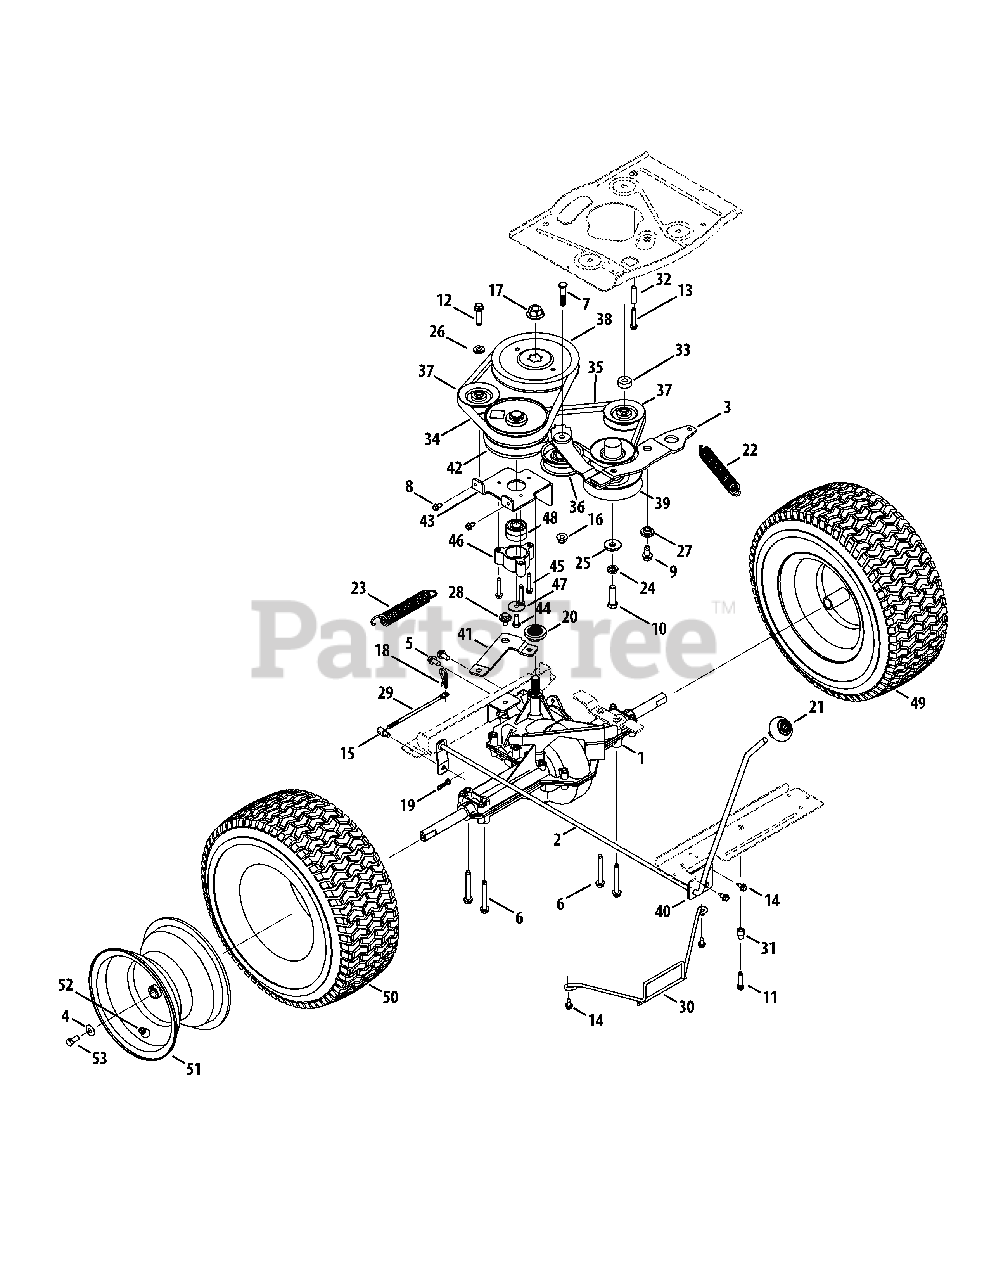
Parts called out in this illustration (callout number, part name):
1	Transmission Assembly
2	Shift Handle Assembly
3	Drive Assembly Idler
4	Beveled Washer, .340 x .872 x .060
5	Tap Screw, 5/16-18, .750
6	Tap Screw, 5/16-18, 2.50
7	Hex Head Scew, 3/8-16, 1.62
8	Tap Scew, 1/4-20, 0.500
9	Tap Screw, 3/8-16, 0.750
10	Hex Head Screw, 7/16-20, 1.50
11	Tap Screw, 1/4-20, 1.250
12	SEMS Tap Screw, 3/8-16, 1.500
13	Tap Screw, 1/4-20, 1.625
14	Tap Screw, 1/4-20 x .625
15	Adjustable Ferrule, 1/4-20 X 1.00
16	Flange Lock Nut, 3/8-16
17	Flange Nut, 9/16-18
18	Internal Cotter Pin, .125 Dia.
19	Bow-Tie Cotter Pin
20	Pulley Hub, 5/8 Spline
21	Shift Knob
22	Extension Spring, .94 Dia. X 6.74 Lg.
23	Extension Spring, .97 OD X 6.18
24	Split Lock Washer, 7/16
25	Flat Washer, .450X1.250X.164
26	Flat Washer, .407X.812X.135
27	Shoulder Spacer, 1.00 X .38 X .38
28	Shoulder Spacer, .560x.165, 5/16-18
29	Shift Rod
30	Deck Belt Keeper, 30"
31	Stepped Spacer, .265 ID X .750
32	Spacer, .260 X .372 X 1.420
33	Spacer, .406 ID X 1.00 OD X .38
34	V-Belt, 5L:35.25
35	V-Belt, 5L:35.28
36	Flat Idler Pulley, 2.75 OD
37	V-Type Idler Pulley, 3.06
38	V-Type Pulley, 6.56
39	Engine Pulley, 4.46 / 3.39
40	Front Support Shift Bracket
41	Rear Idler Arm Bracket
42	Variable Speed Pulley Assembly
43	Variable Bracket
44	Hex Head Lock Screw, 5/16-24:.750
45	Tap Screw, 1/4-20:1.500
46	Bearing Cup
47	Flat Washer, .330x1.250x.060
48	Ball Bearing, 17 X 40 X 12
49	Complete Wheel Assembly
50	Tire, 16 x 6.5 x 8 Sq. Shldr.
51	Rim Assembly, 8.0 x 5.38
52	Air Valve
53	Hex Head Screw, 5/16-24, 7.50
